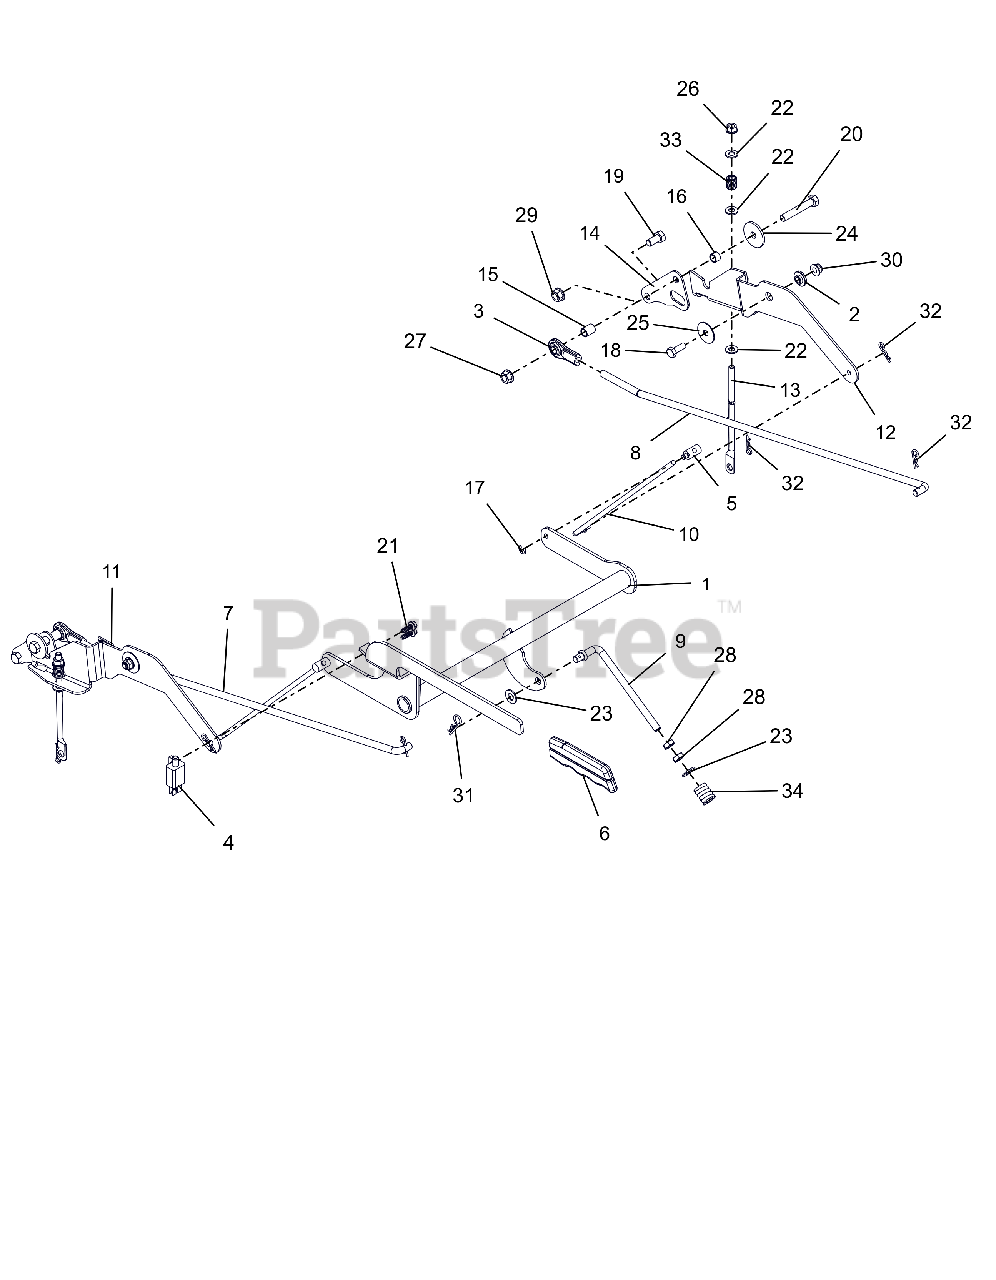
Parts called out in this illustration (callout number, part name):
1	WLDMT, BRAKE LEVER
2	BSHG, FLG .325X.499X.26X.88
3	ROD END, .38 RH
4	SWITCH- DOUBLE POLE N.O./N.O.
5	TRUNION, 1/4-20
6	GRIP, PARKING BRAKE (YELLOW)
7	STEERING, LINKAGE RH
8	STEERING, LINKAGE LH
9	LINK, OVER CENTER, PARKING BRK
10	LINK, BRAKE ARM
11	INTERLOCK, RH BRAKE LINK
12	INTERLOCK, LH BRAKE LINK
13	LINK, BRAKE COG
14	PLATE, TRANSAXLE ADAPTOR
15	SPCR, SLV .385X.500X.652
16	SPCR, SLV .385X.500X.350
17	RG-RTNG-EXT .250X.025
18	BLT, HEX .31-18X.875 G5 ZCC
19	BLT,HEX .38-16X.75 G5 ZCC
20	BLT,HEX .38-16X2.25 G5 ZCC
21	SCR, PLASTITE .25-10X.75 ZCC
22	WSHR,FLT .344X.688X.065 ZCC
23	WSHR,FLT .406X.812X.065 ZCC
24	WSHR, FLT .380X1.50X.125 ZCC
25	WSHR, FLT .347X1.254X.048 ZCC
26	NUT,LK-CTR-FLG .31-18 GF ZCC
27	NUT-LK-CTR-FLG .375-16 GF ZCC
28	NUT-JAM .375-16 G2 ZCC
29	NUT-LK-TOP-FLG .38-16 ZC120
30	NUT,LK-NYL-FLG .31-18 G5ZC120
31	PIN-HAIR CTR .09 X 1.50 YWZC
32	PIN, HAIR #213 .08X1.19 ZCC
33	SPRING, COMPRESSION
34	SG-COMP .187X.56X1.62
